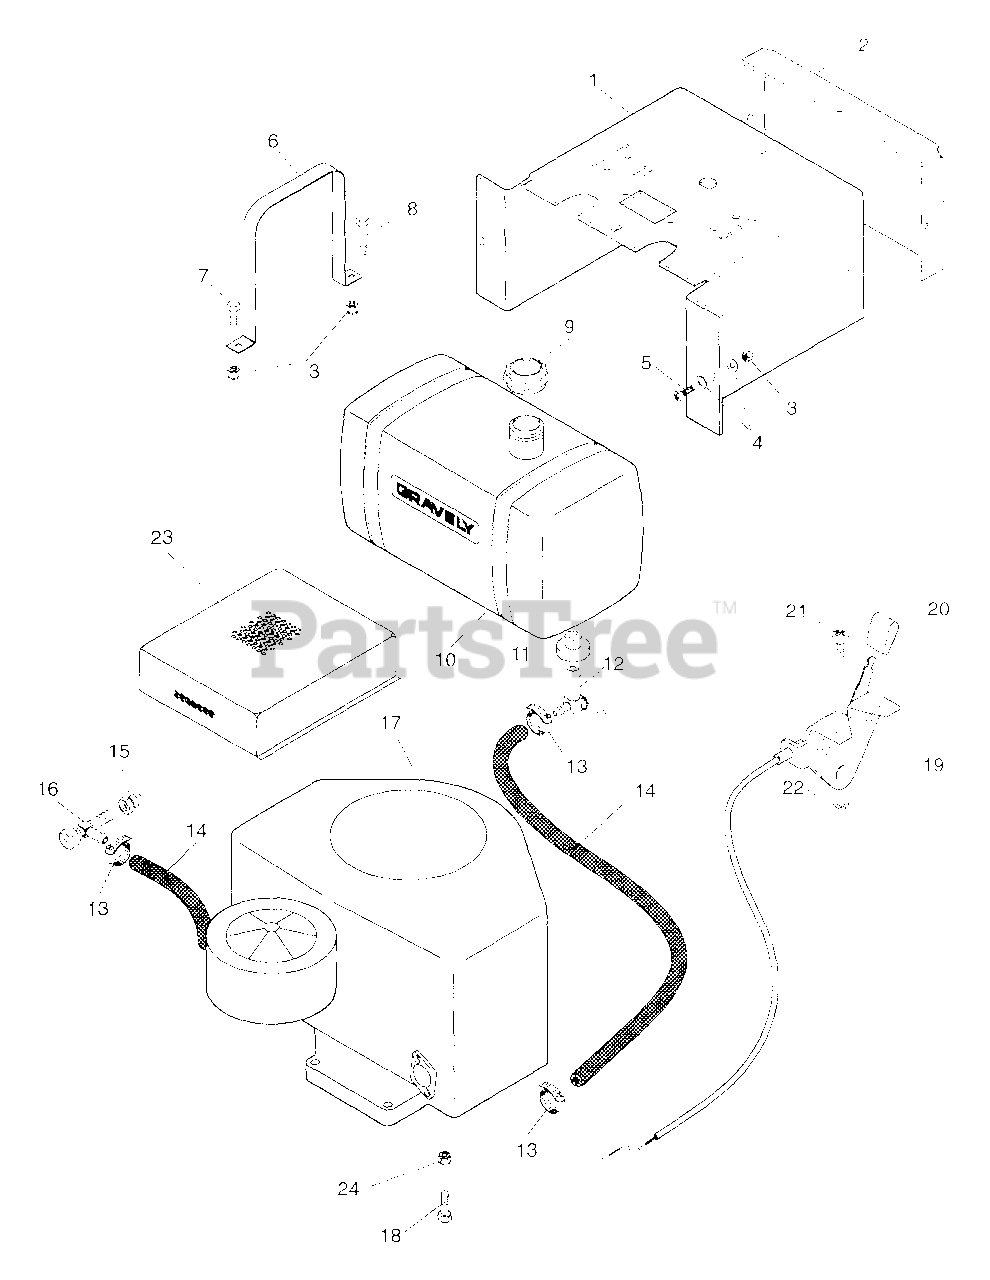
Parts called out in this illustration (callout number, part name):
1	Panel, Silkscreen
2	Cover, Instrument Panel
3	Nut-Locking-Nylon .250-20 Grade 2
4	Washer-Flat-Steel .281 x .620 x .065
5	Screw Machine .25-20
6	Strap, Fuel Tank
7	Bolt-Hex .25-20 x .63
8	Bolt-Hex .25-20 x 1.00 Grade 5
9	Cap, Fuel Tank
10	Tank, Fuel PM 200
11	Bushing
12	Valve, Ball Shut-Off
13	Hose Clamp
14	Gas Line-Bulk
15	Adapter, Oil Drain
15	Module, Time Delay
16	Cock, Oil Drain
17	Engine, 20 HP Kohler CV2OS
17	Engine, Kaw 18HP
18	Screw-Tapping .375-16 x 1.0
18	Bolt-Hex M8 x 1.25 x 25MM
18	Bolt-Hex M10 x 1.5 x 16MM
19	Assembly, Throttle Control
20	Knob
21	Screw-Machine 10-32 x .50
22	Nut-Locking 10-32
23	Weldment, Pre-Cleaner Screen
24	Nut-Hex MB x 1.25
